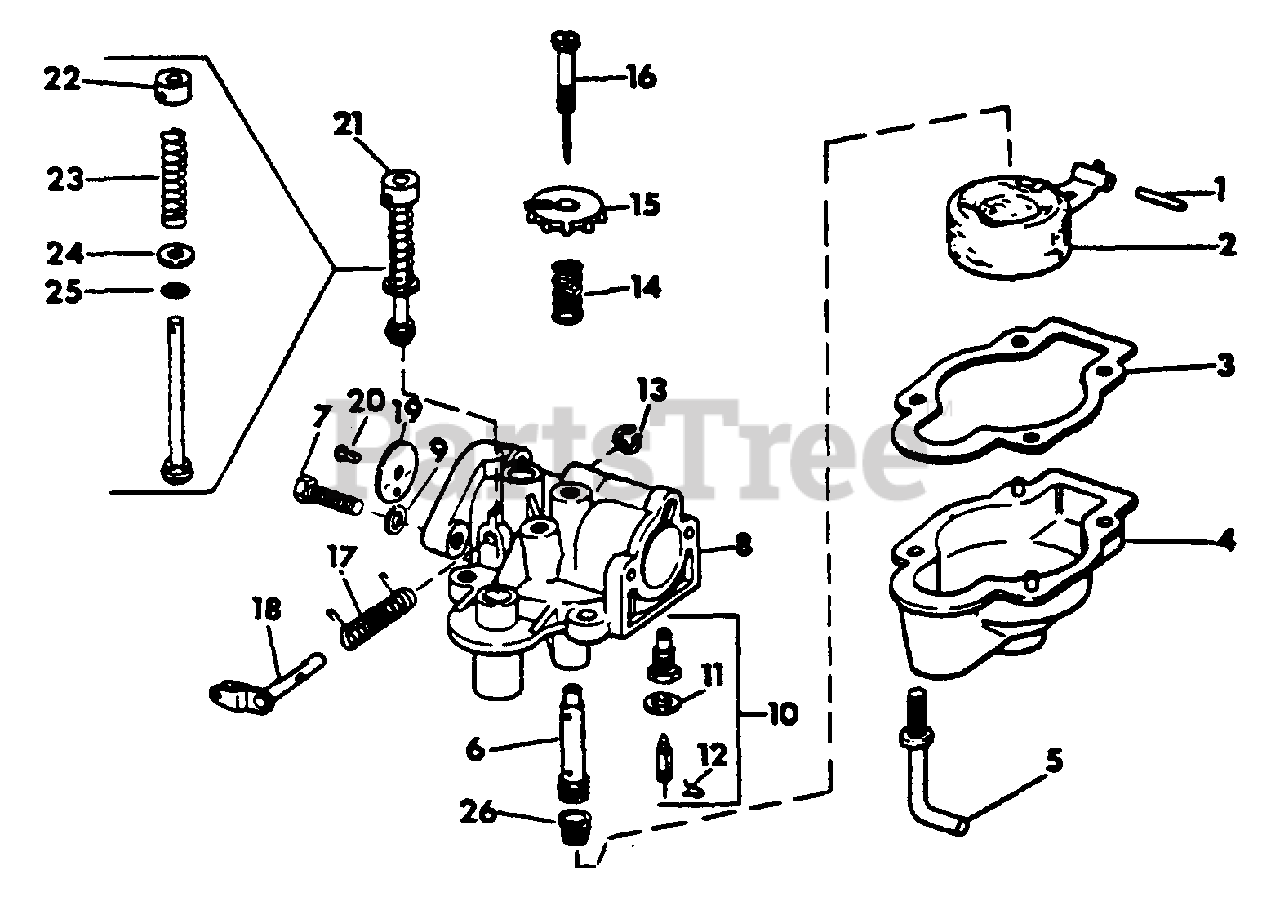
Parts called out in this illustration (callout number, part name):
1	PIN, FLOAT ARM HINGE
3	GASKET, FLOAT CHAMBER
4	CHAMBER, FLOAT
5	SCREW, FLOAT CHAMBER
8	BODY ASSY, CARBURETOR
10	FLOAT VALVE & SEAT
11	WASHER, FLOAT VALVE SEAT
14	SPRING, NEEDLE ADJ
15	KNOB, NEEDLE ADJ
17	SPRING, THROTTLE
18	THROTTLE SHAFT & LEVER ASSY
19	DISC, THROTTLE
20	SCREW, THROTTLE SHAFT DISC
21	PRIMER ASSY
22	KNOB, PRIMER
23	SPRING, COMPRESSION
